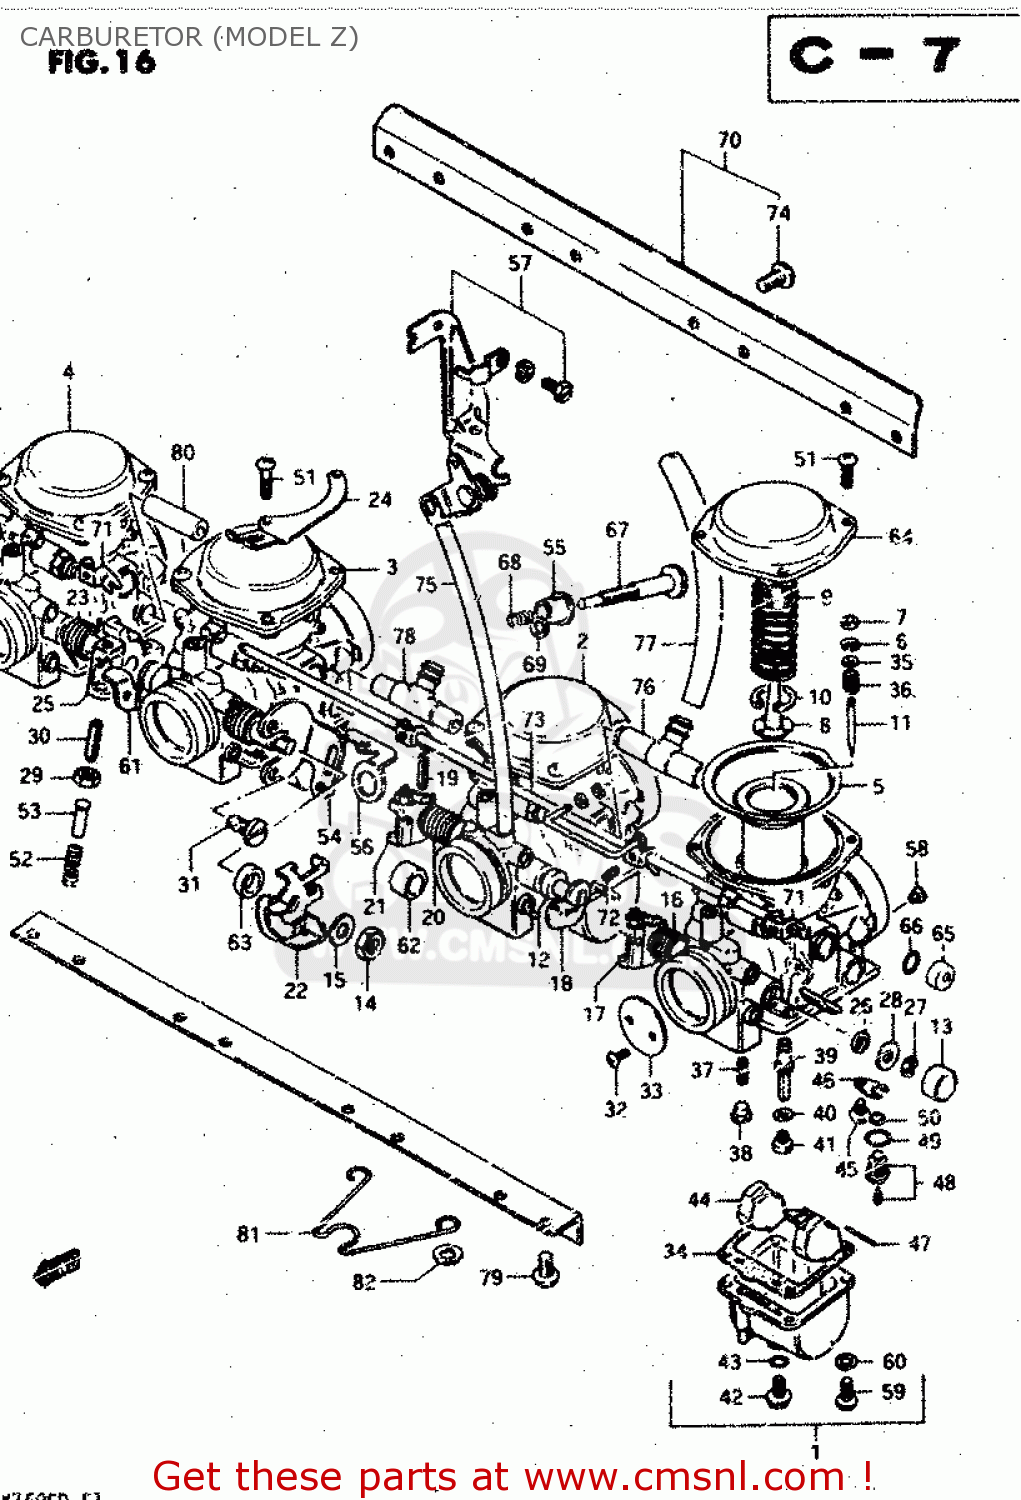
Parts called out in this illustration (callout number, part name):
1	CARBURETOR, LH
2	CARBURETOR, ML
3	CARBURETOR, MR
4	CARBURETOR, RH
5	DIAPHRAGM
6	CLIP,NEEDLE
7	RING
8	HOLDER,GUIDE
9	SPRING
10	E RING
11	NEEDLE, JET (5057-2)
12	GASKET
13	CAP
14	NUT 8MM
15	WASHER
16	SPRING,THROTTLE SHAFT
17	SHAFT,THROTTLE
18	SHAFT ASSEMBLY
19	PIN,THROTTLE SHAFT
20	SPRING,THROTTLE SHAFT
21	LEVER,THROTTLE SHAFT
22	LEVER ASSEMBLY,THROTTLE
23	SPRING,THROTTLE SHAFT
24	BRACKET,THROTTLE CABLE
25	SHAFT,THROTTLE
26	SEAL
27	E RING
28	GASKET,THROTTLE SHAFT (NAS)
29	NUT
30	SCREW
31	SCREW
32	SCREW
33	VALVE,THROTTLE (BUTTERFLY)
34	GASKET,FLOAT CHAMBER (NAS)
35	WASHER
36	SPRING
37	JET, PILOT (42.5)
38	PLUG,NEEDLE JET
39	JET, NEEDLE (X-2)
40	WASHER,NEEDLE NOZZLE
41	JET,MAIN(112.5)
42	PLUG,DRAIN
43	GASKET (NAS)
44	FLOAT
45	SCREW 4X6
46	PLATE,NEEDLE VALVE FITING
47	PIN,FLOAT
48	VALVE ASSEMBLY,NEEDLE
49	O-RING,NEEDLE VALVE
50	FILTER
51	SCREW
52	SPRING,THROTTLE SCREW
53	PIN,THROTTLE LEVER
54	BRACKET,THROTTLE ADJUST
55	BUSH
56	BRACKET,THROTTLE ADJUST
57	BRACKET ASSY
58	JET,AIR
59	SCREW
60	LOCK WASHER
61	SHAFT,THROTTLE
62	RING
63	RING
64	COVER,DIAPHRAGM
65	CAP,STARTER VALVE
66	O RING
67	SCREW
68	SPRING
69	WASHER
70	FLANGE ASSY
71	LEVER
72	SCREW
73	SHAFT,STARTER
74	SCREW
75	HOSE
76	NIPPLE
77	HOSE,CARBURETOR
78	HOSE
79	SCREW
80	NIPPLE
81	CLIP
82	WASHER
